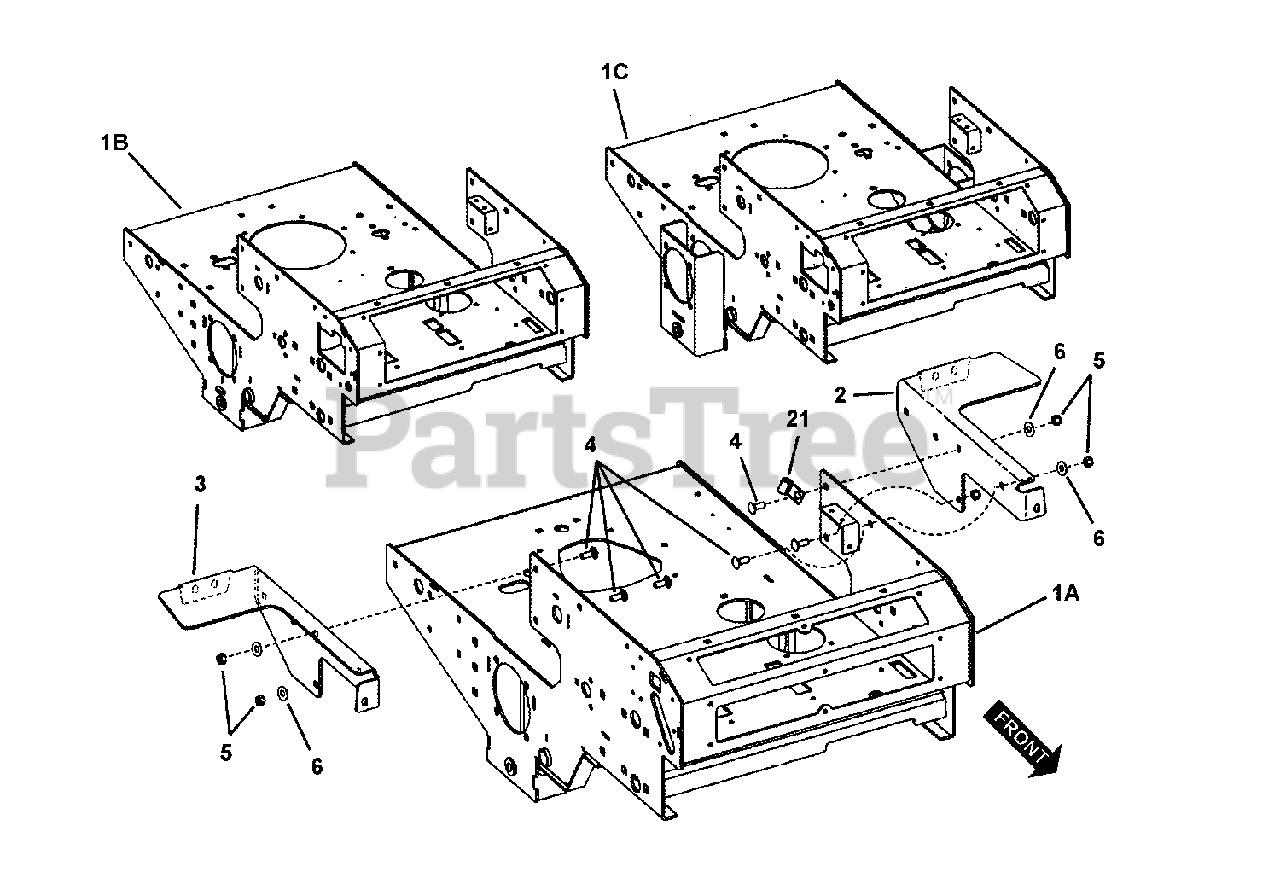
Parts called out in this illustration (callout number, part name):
1A	WELDMENT, Rear Frame
1B	WELDMENT, Rear Frame
1C	WELDMENT, Rear Frame
2	WELDMENT, Left Hand Fuel Tank Bracket
3	WELDMENT, Right Hand Fuel Tank Bracket
4	BOLT, 3/8-16 x 1" Square Neck Carriage GR5
5	NUT, 3/8-16 HEX NYLON LOCK
6	WASHER, 3/8" Flat
21	CLIP, Open 3/8" Cushioned
